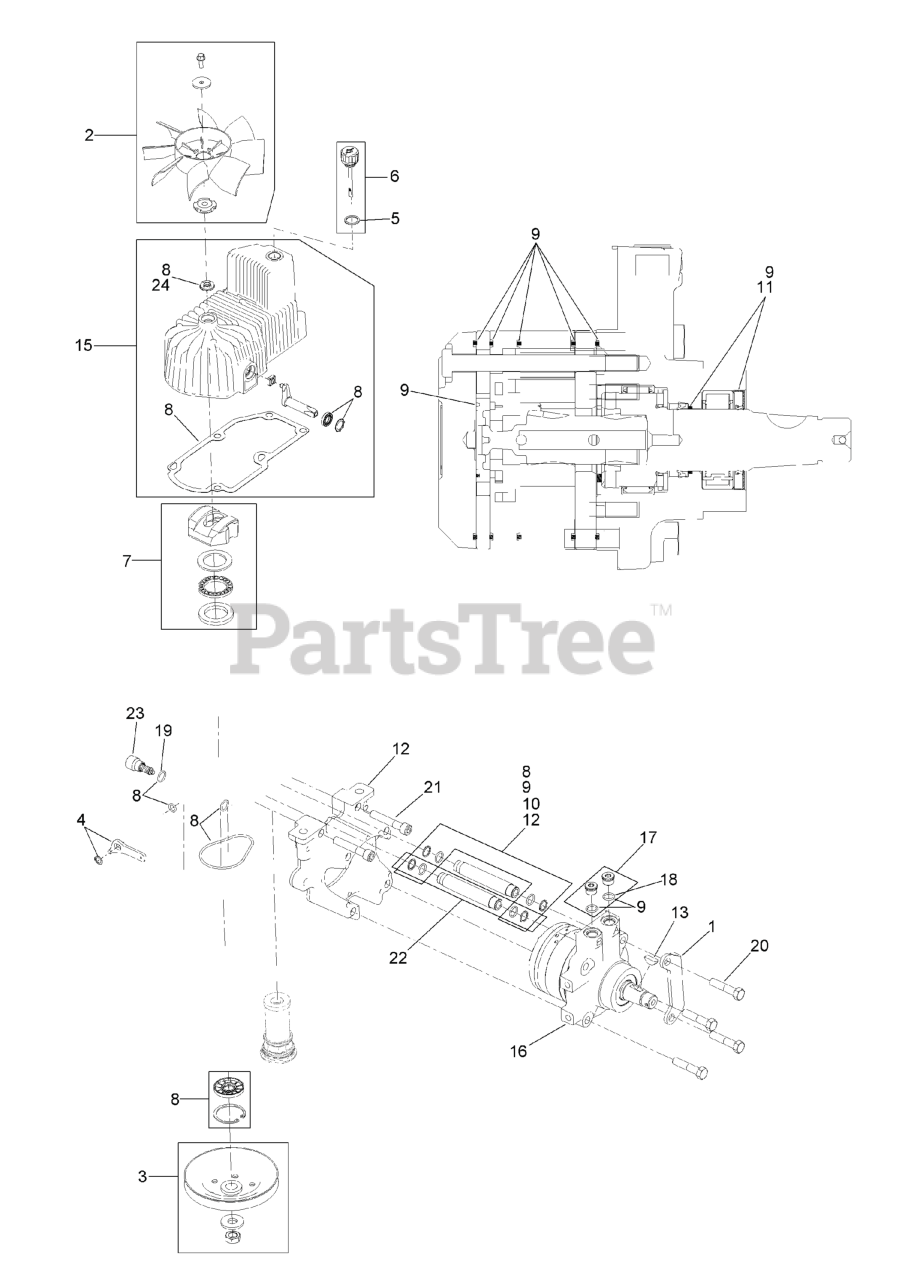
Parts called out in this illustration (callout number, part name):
1	MOUNT-SHOE, HORSE
2	FAN KIT
3	PULLEY KIT
4	HANDLE-BYPASS VALVE, HYDRO
5	GASKET-DIPSTICK, HYDRO
6	DIPSTICK-HYDRO W/GASKET
7	SWASH BLOCK KIT
8	PUMP SEAL KIT
9	MOTOR SEAL KIT
10	TUBE SEAL KIT
11	OUTPUT SHAFT SEAL KIT
12	NOSE CUP-UHT
13	KEY-WOODRUFF
15	HOUSING-HYDRO, RH
16	MOTOR-HYDRAULIC, RH 280CC
17	MAGNETIC PLUGS SERVICE KIT
19	O-RING-CHECK VALVE
20	SCREW HH
21	SCREW-HSH
22	HYDRAULIC TUBE KIT
23	SHOCK VALVE, 16CC HYDRO
24	SEAL-FAN DRIVE
25	Kit, Pump Section 16Cc RH
26	Kit, Rotating Grp 16Cc RH
99	PULLER-PULLEY
